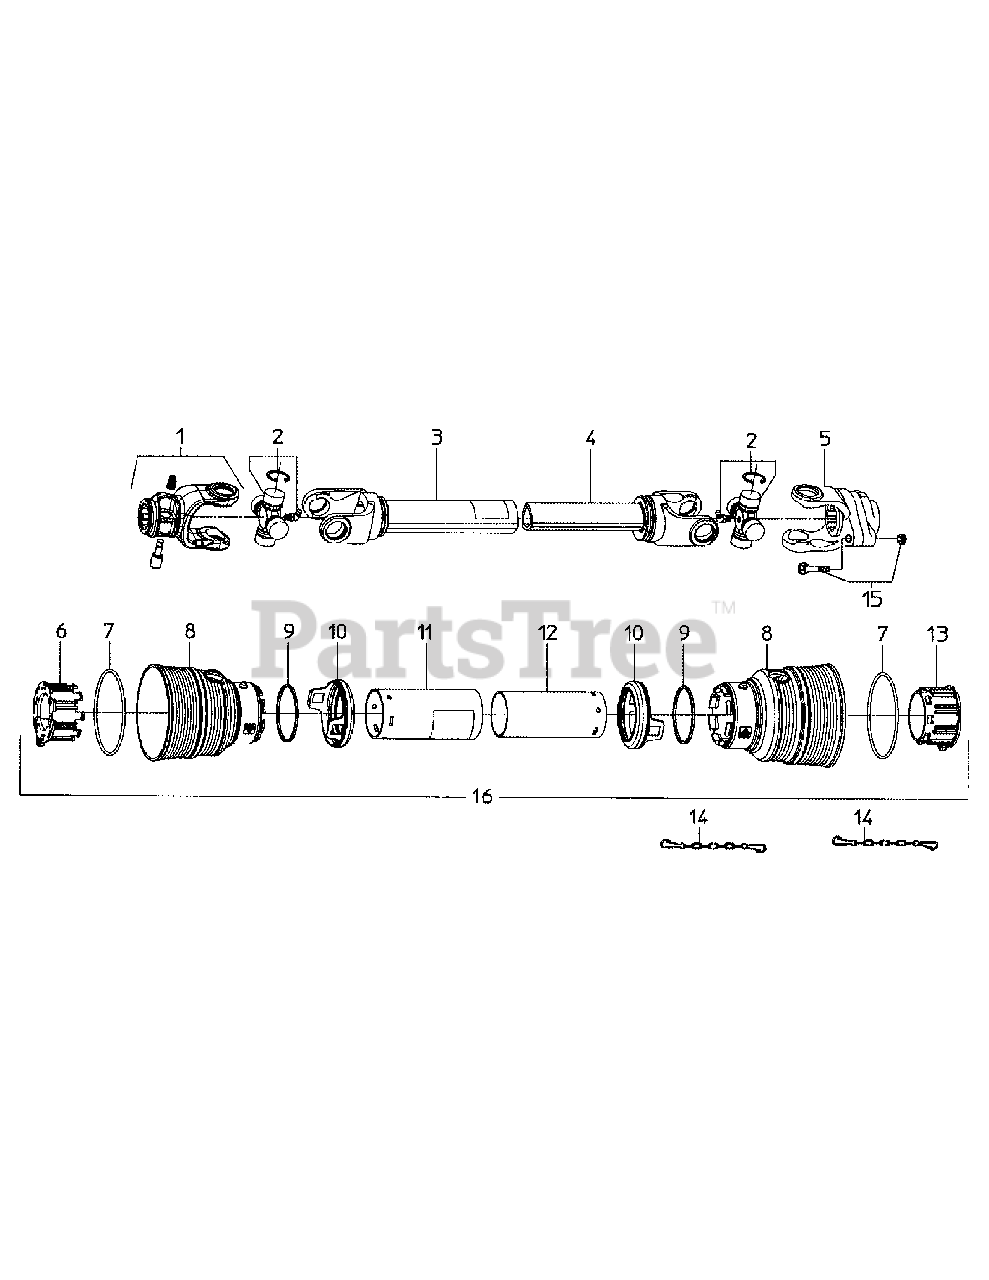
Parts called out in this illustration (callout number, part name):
1	PTO Yoke
2	Cross & Bearing
5	Shearpin coupler
6	Outer locking ring
7	Stiffening ring
10	Safety sleeve
11	Female tube shield
12	Male tube shield
13	Inner locking ring
14	Chain
16	Complete shielding
